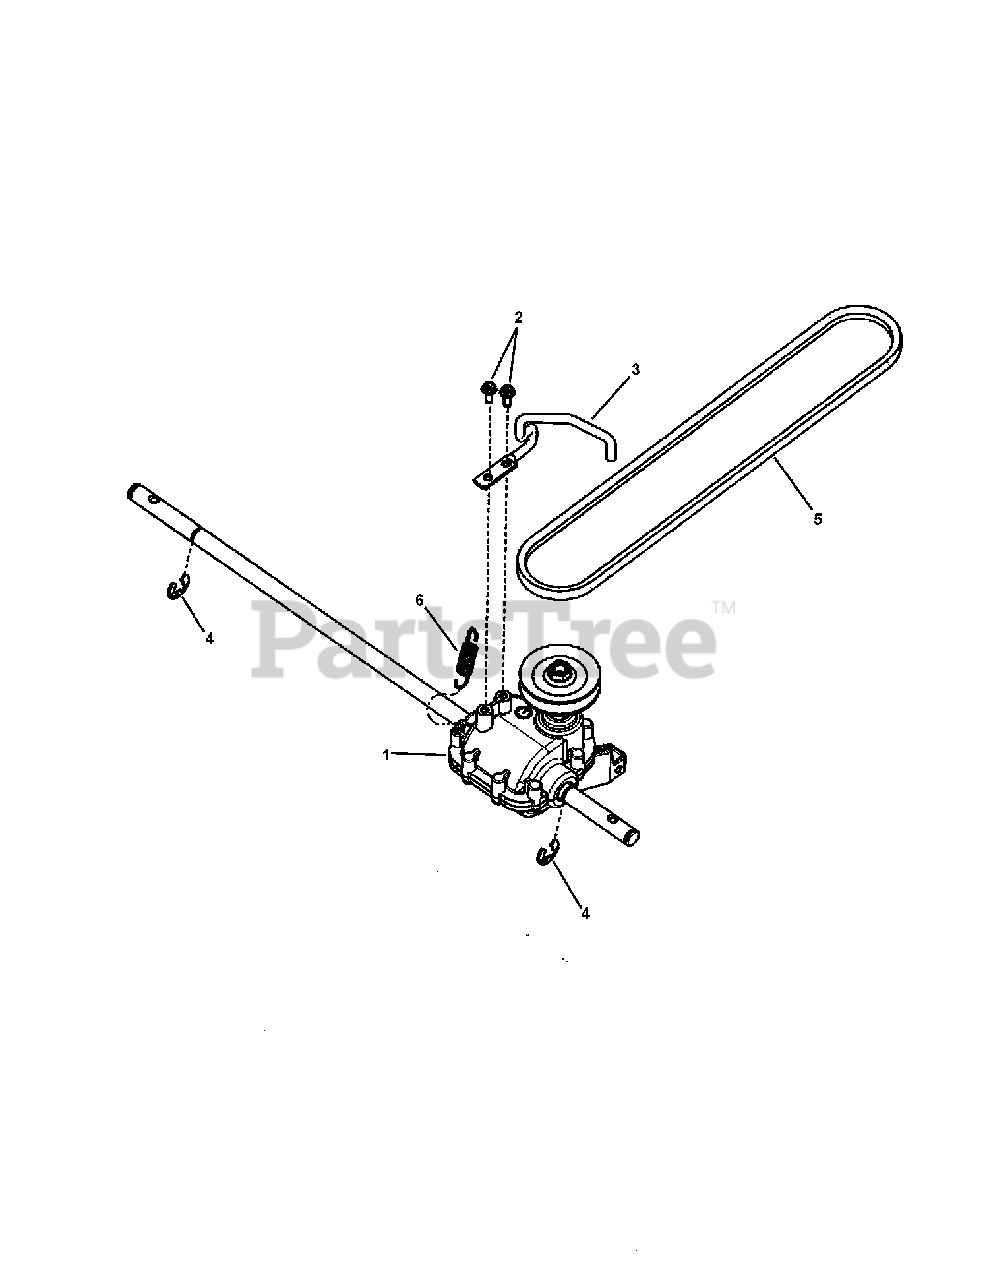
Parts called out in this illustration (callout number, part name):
1	TRANSMISSION, Varaible Speed, Front Wheel Drive
2	SCREW, #10-14 x 1/2" Hex Washer Self-Tap, Plastite
3	GUIDE, Belt, FWD
4	RETAINING RING, .392 Ext.
5	BELT, Traction Drive, 22" WBM, FWD (3L Sect., 32.40 Effective Length)
6	SPRING, Tension, FWD React Drive
